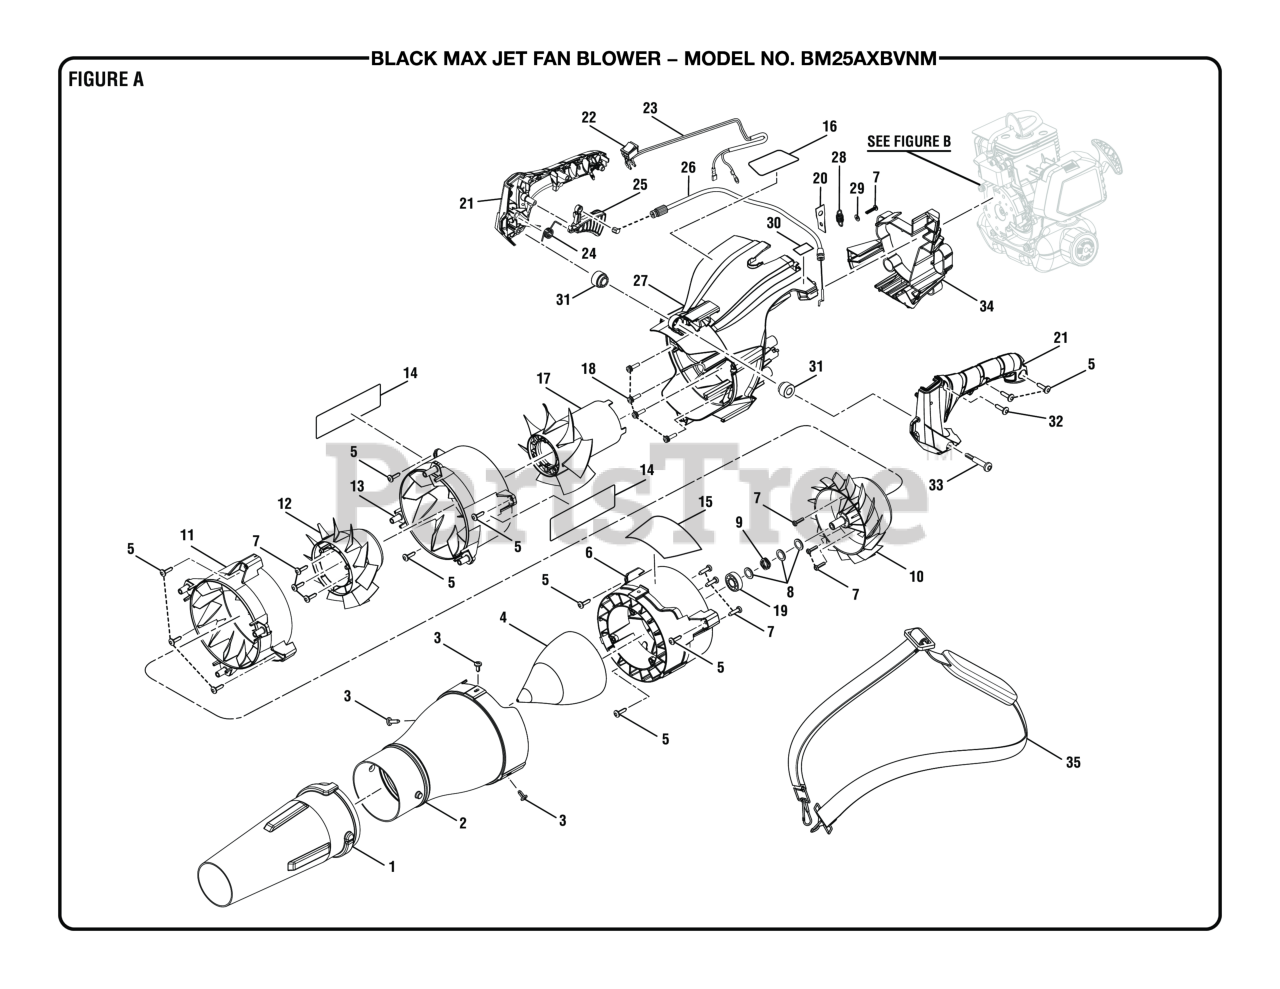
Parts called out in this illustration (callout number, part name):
1	Blower End Nozzle
2	Reducer Nozzle
3	Vacuum Tube Screw (10-14 x 1/2 in., T25 Torx Truss Hd. T.F.)
4	Reducer Cone
5	Screw (10-14 x 19 mm, T25 Torx Truss Pan Hd. T.F.)
6	Axial Stator w/Bearing Assembly Stage 3
7	Screw (M4 x 1.41 mm x 18 mm, T20 Torx Pan Hd. T.F)
8	Washer (OD18 x ID12.15 x 1.5t)
9	Wave Spring
10	Axial Fan (Stage Three)
11	Axial Stator (Stage 2)
12	Axial Fan (Stage Two)
13	Axial Stator (Stage 1)
14	Tube Branding Label
15	Logo Label (Full Crank, 2 cycle)
16	Warning Icon Label
17	Axial Fan (Stage 1)
18	Cap Screw w/Washer (M5 x 16 mm, T25 Torx Soc. Hd.)
19	Ball Bearing (6001-zz)
21	Handle Assembly
22	Stop Switch (Momentary Contact)
23	Wiring Harness w/Fiber Sleeve
24	Torsion Spring (Throttle Trigger)
25	Throttle Trigger
26	Throttle Cable
27	Intake Housing
28	Isolator Spring
29	Flat Washer (OD10 x ID42 x 1t)
30	Primer Bulb Location Label
31	Bushing (Front Isolator)
32	Screw (#10-14 x 3/4 in, T25 Torx Pan Hd. T.F.)
33	Shoulder Screw (M5 x 40 mm, T25 Torx Truss Hd. T.F.)
34	Intake Guard
35	Shoulder Strap
